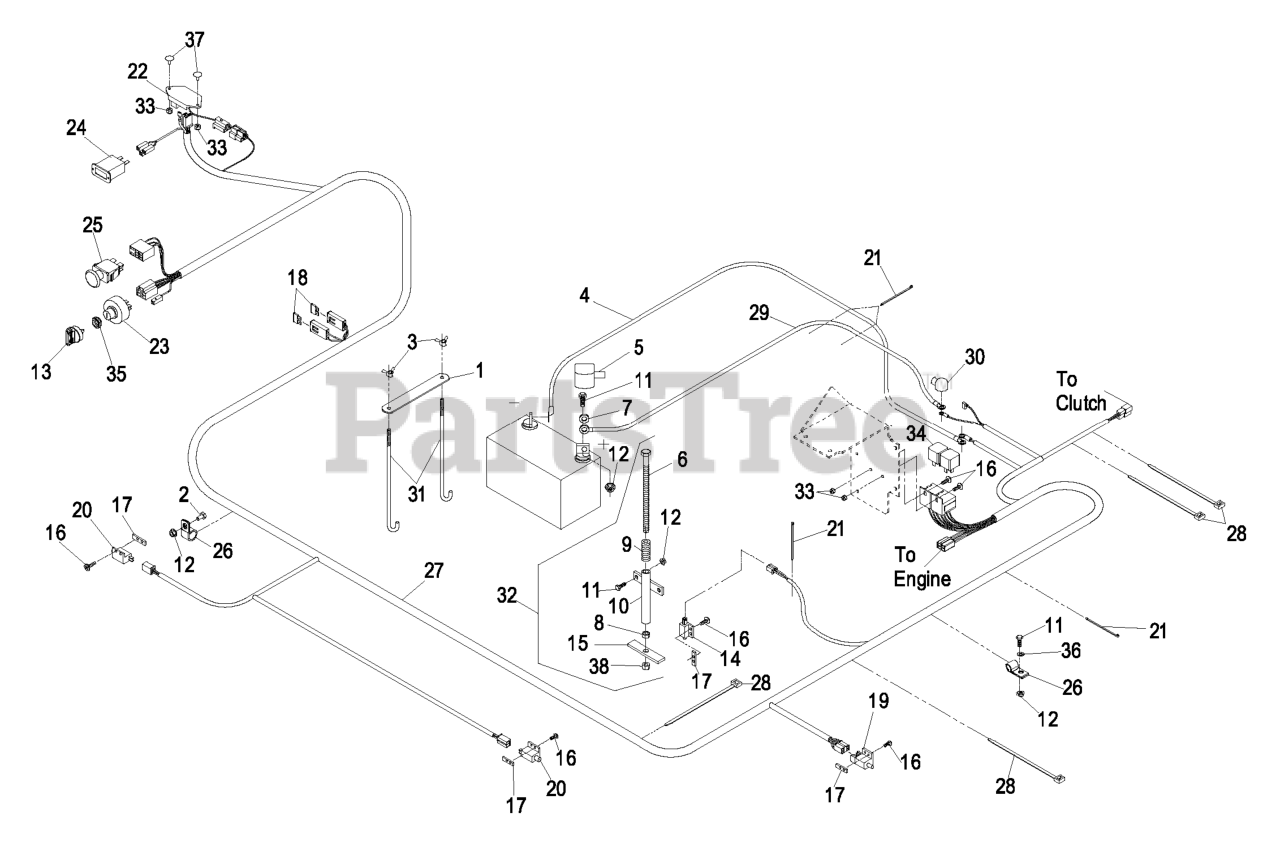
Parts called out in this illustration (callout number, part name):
1	STRAP-HOLDDOWN, BATTERY
2	SCREW-HH
3	WINGNUT
4	WIRE-GROUND
6	SCREW-HH
7	WASHER-FLAT
8	NUT-HEX
9	SPRING-SWITCH, SEAT
10	MOUNT-SPRING, SEAT
11	SCREW-HH
13	KEY-IGNITION
14	SWITCH-CLOSED, NORMALLY
15	PLATE-SWITCH, SEAT
16	SCREW-PPH
17	PLATE-TAPPED
18	FUSE-BLADE TYPE, 20 AMP
20	SWITCH-OPEN, NORMALLY
21	TIE-CABLE
22	MODULE-DELAY, SEAT
24	METER-HOUR
25	SWITCH-PTO
26	CLIP-LOOM
27	HARNESS, WIRE LAZER KC
28	TIE-PLASTIC
30	INSULATOR-SOLENOID
31	BOLT-HOLDDOWN
32	ASM,SEAT SWITCH ACTUATOR
33	NUT-LOCK, NI
35	NUT-SWITCH, IGNITION
36	WASHER-FLAT
37	BOLT-CARR
38	NUT-LOCK, NI
